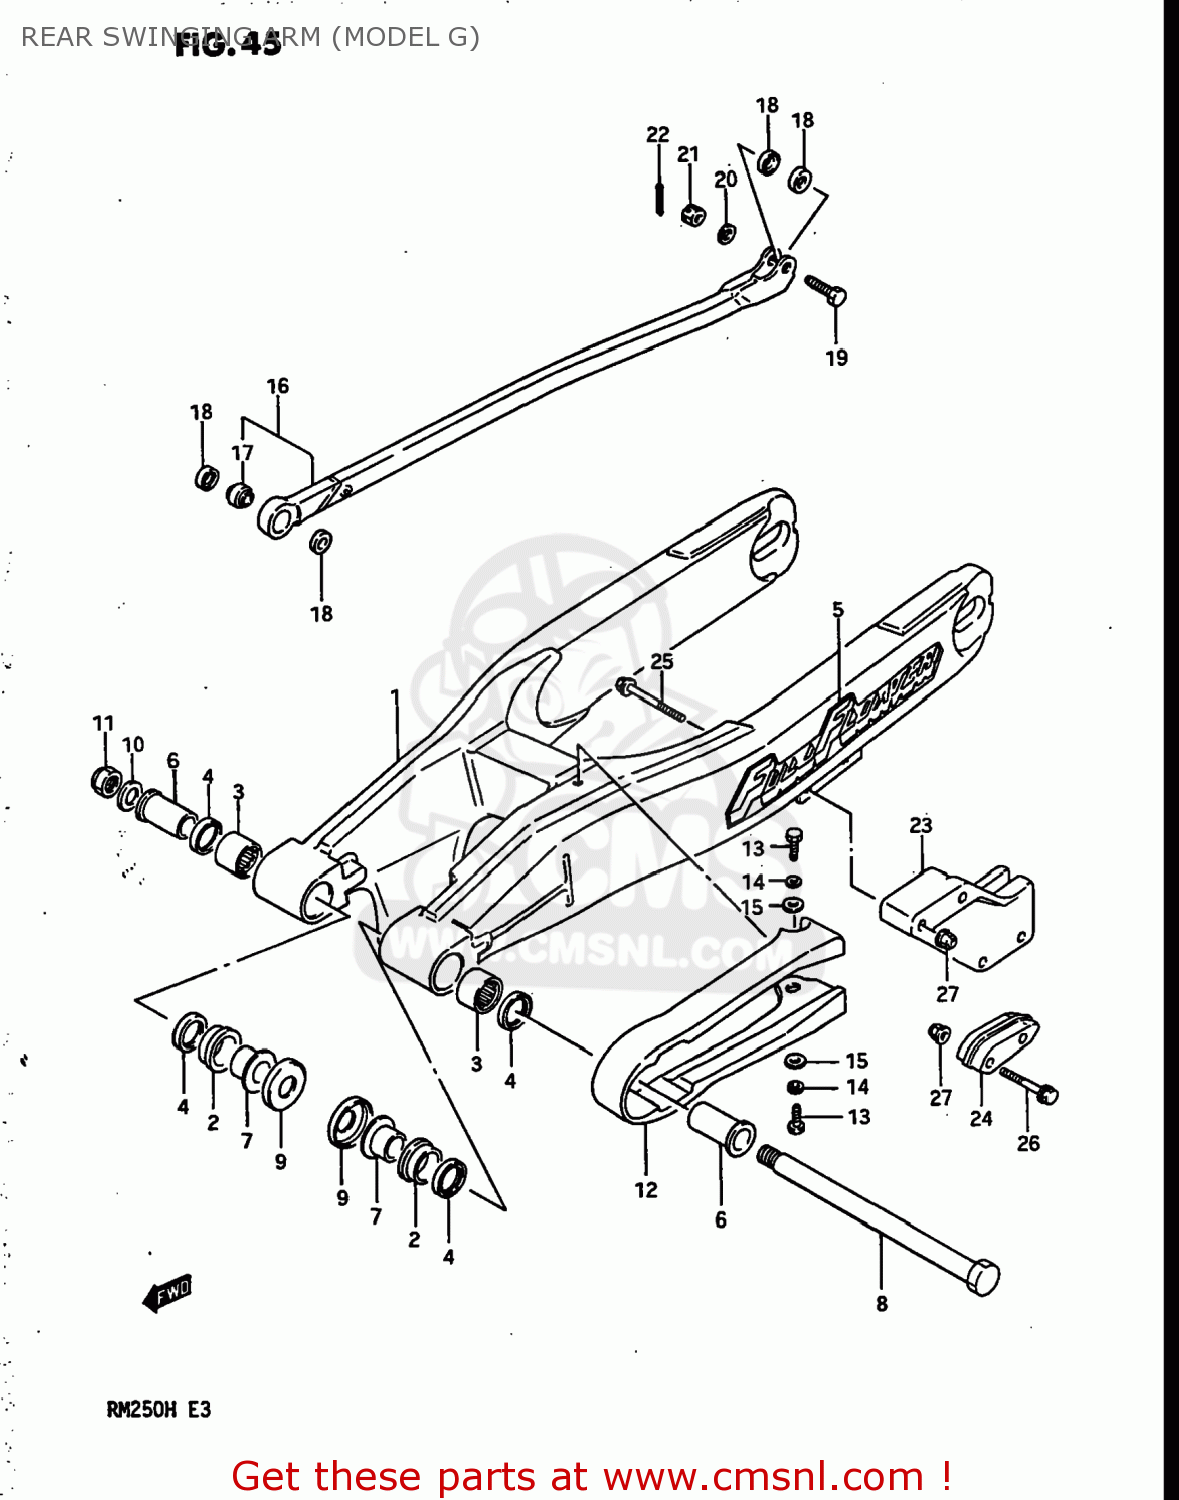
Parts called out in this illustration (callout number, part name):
1	SWING ARM ASSEMBLY,REAR
2	BUSHING,REAR SWING ARM PIVOT
3	BEARING(20X27X20)
4	OIL SEAL
5	LABEL (FRONT CARRIER WARNING)
6	SPACER,RR SWINGING ARM PIVOT
7	SPACER,RR SWGARM PIVOT INNER
8	SHAFT,RR SWINGINGARM PIVOT
9	COVER,RR SWGARM DUST SEAL
10	WASHER(14.5X29X2.3)
11	NUT
12	BUFFER,CHAIN TOUCH DEFLECTOR
13	BOLT
14	WASHER,LOCK
15	WASHER(6.5X16X1.2)
16	TORQUE LINK SET,REAR
17	SPHERICAL BEARING,TORQUE
18	19
19	BOLT 8X29.5
20	WASHER
21	NUT 8MM
22	PIN 20X20
23	GUIDE,CHAIN
24	DEFENSE,CHAIN GUIDE
25	BOLT
26	BOLT,UNDER
27	NUT
